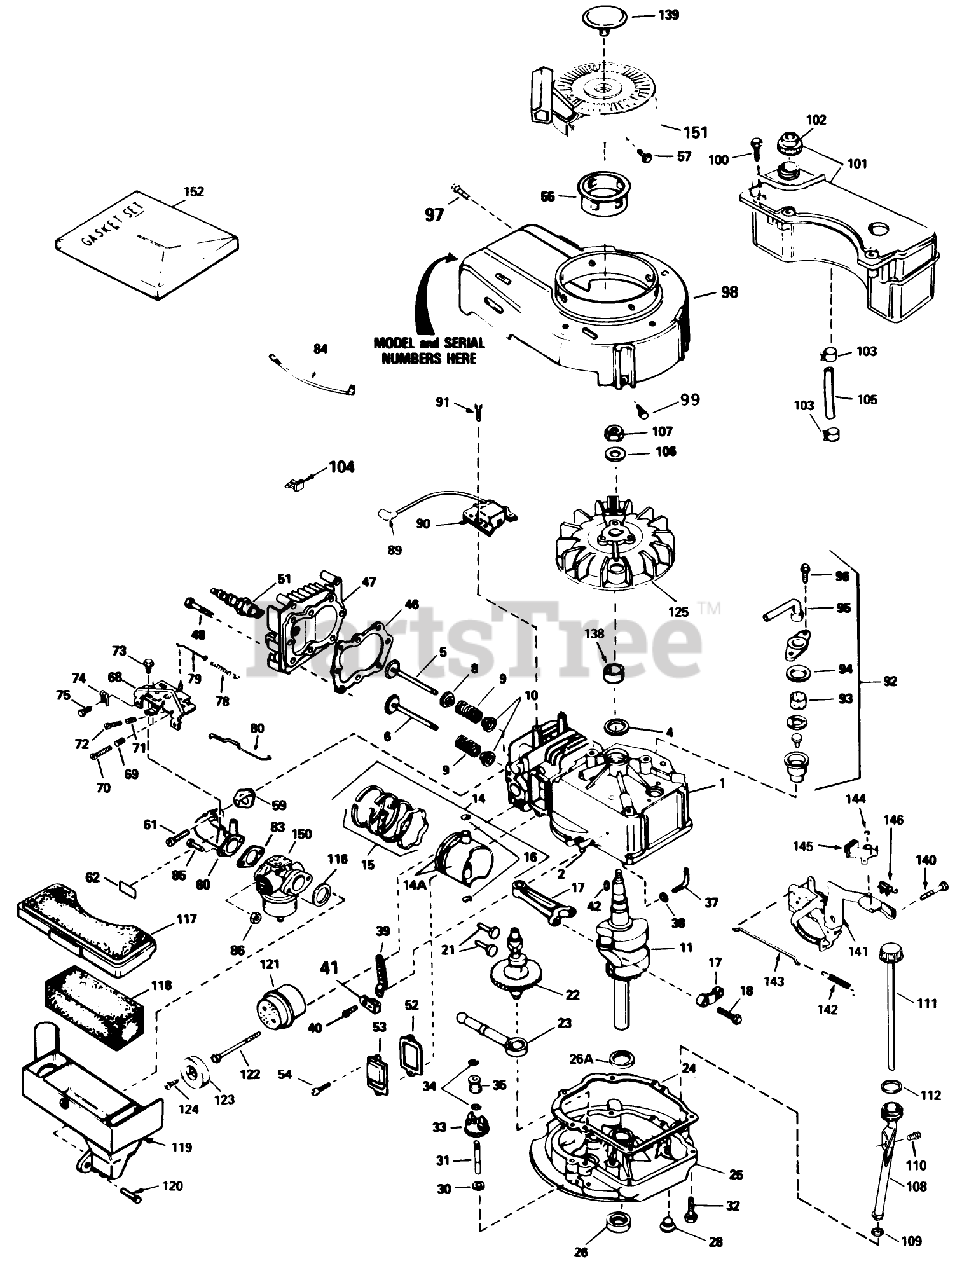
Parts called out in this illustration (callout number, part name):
1	Cylinder Assy. (Incl. #24)
2	Pin-Dowel
4	Seal-Oil
5	Valve, Intake (Std.) (Incl. Ref. #40)
5	Valve, Intake (1/32" oversize)(Incl. No. 40)
6	Valve, Exhaust (Std.)(Incl. No. 40)
6	Valve, Intake (1/32" oversize)(Incl. No. 40)
8	Seal Assy., Intake
9	Spring-Valve
10	Cap-Valve, Spring
11	Crankshaft
14	Piston-Pin Ring Assy. (Std.)(Incl. Ref. #16A, 17 18)
14	Piston-Pin Ring Assembly (.010 oversize)(Incl. Ref. #16A, 17 18)
14	Piston, Pin Ring Assy. (.020 Oversize)(Incl. Ref. #13A, 14, 15)
14A	Piston Pin Assy. (Std.)(Incl. Ref. #14)
14A	Piston Pin Assembly (.010 oversize)(Incl. Ref. #18)
14A	Piston Pin Assy. (.020 Oversize) (Incl. Ref. #14)
15	Ring Set-Piston (Std.)
15	Ring Set, Piston(.0100versize)
15	Ring Set (.020" OS)
16	Ring-Retaining, Piston Pin
17	Rod Assy., Connecting (Incl. Ref. #17)
18	Bolt-Rod, Connecting
21	Lifter-Valve
22	Camshaft(Mech.Comp. Release)
23	Oil Pump ASM
24	Gasket
25	Flange-Mounting (Incl. Ref. #26, 27 39)
26	Seal-Oil
26A	Washer-Thrust
28	Plug Oil Drain
30	Washer-Flat
31	Shaft-Governor
32	Screw (1/4-20 x 1-1/4)
33	Governor Gear ASM
34	Ring-Retaining
35	Spool-Governor
37	Rod, Governor (Incl. No. 36)
38	Washer-Flat
39	Governor Lever
40	Screw
41	Clamp-Lever, Governor
42	Key-Flywheel
46	63573 GIL 42 SNWTHW
47	Head-Cylinder
48	Screw (5/16-18x1-1/2)
51	Spark Plug-Resistor (R J19 L M)
52	Gasket-Breather
53	Cover-Valve
54	Screw
55	Hub-Starter
57	Screw, Hex Hd.
59	Gasket-Intake
60	Pipe-Intake (Incl. Ref. #59)
61	Screw (1/4-20 x 1)
62	Decal-Primer
68	Control Assy.-Remote Speed (Incl. Ref. #69 thru 72 76)
69	61709/GIL1515A/95-5
70	Screw
71	Spring-Compression
72	Screw
73	Screw (10-24 x 9/16)
74	Conduit
75	Screw (10-32 x 3/8)
78	Spring Governor
79	2035A67 ADD.ASSEMBL
80	Link-Throttle
83	Gasket
84	Ground Wire
86	Nut and Lock Washer (1/4-28)
89	Cover-Spark Plug
90	Solid State
91	Screw
92	Breather Assy. (Incl. Ref. #46 thru 51)
93	Element-Breather
94	Gasket-Breather
95	Tube, Breaker
96	Screw (10-24 x 9/16)
97	Screw (10-24 x 9/16)
98	Housing-Blower
99	Screw (1/4-20 x 1/2)
100	Screw (10-32 x 35/64)
101	Tank Assembly-Fuel (Incl. Ref. #102)
102	Cap-Fuel
103	Clamp-Line, Fuel
104	Clip-Wire
105	Line-Fuel
106	Washer-Belleville
107	Nut-Flywheel
108	Oil Fill Tube
109	Gasket
110	Screw (10-32 x 1/2)
111	Dipstick
112	O-Ring
116	Gasket-Cleaner, Air
117	Cover-Air Cleaner
118	Filter-Air Cleaner
119	Body Air cleaner
120	Screw
121	B Muffler (Incl. Ref. #122)
122	Screw
123	Cover-Muffler
124	Screw (8-32 x 3/8)
125	Flywheel
138	Spacer
139	Plug Starter
140	Screw (1/4-20 x 3/8)
141	Bracket-S.E. Brake
142	Spring-Extension
143	Link-Control
144	Ring-Retaining
145	Lever-Brake
146	Terminal
150	Carburetor (Incl. Ref. #83)
151	Starter-Rewind
152	Gasket Set
